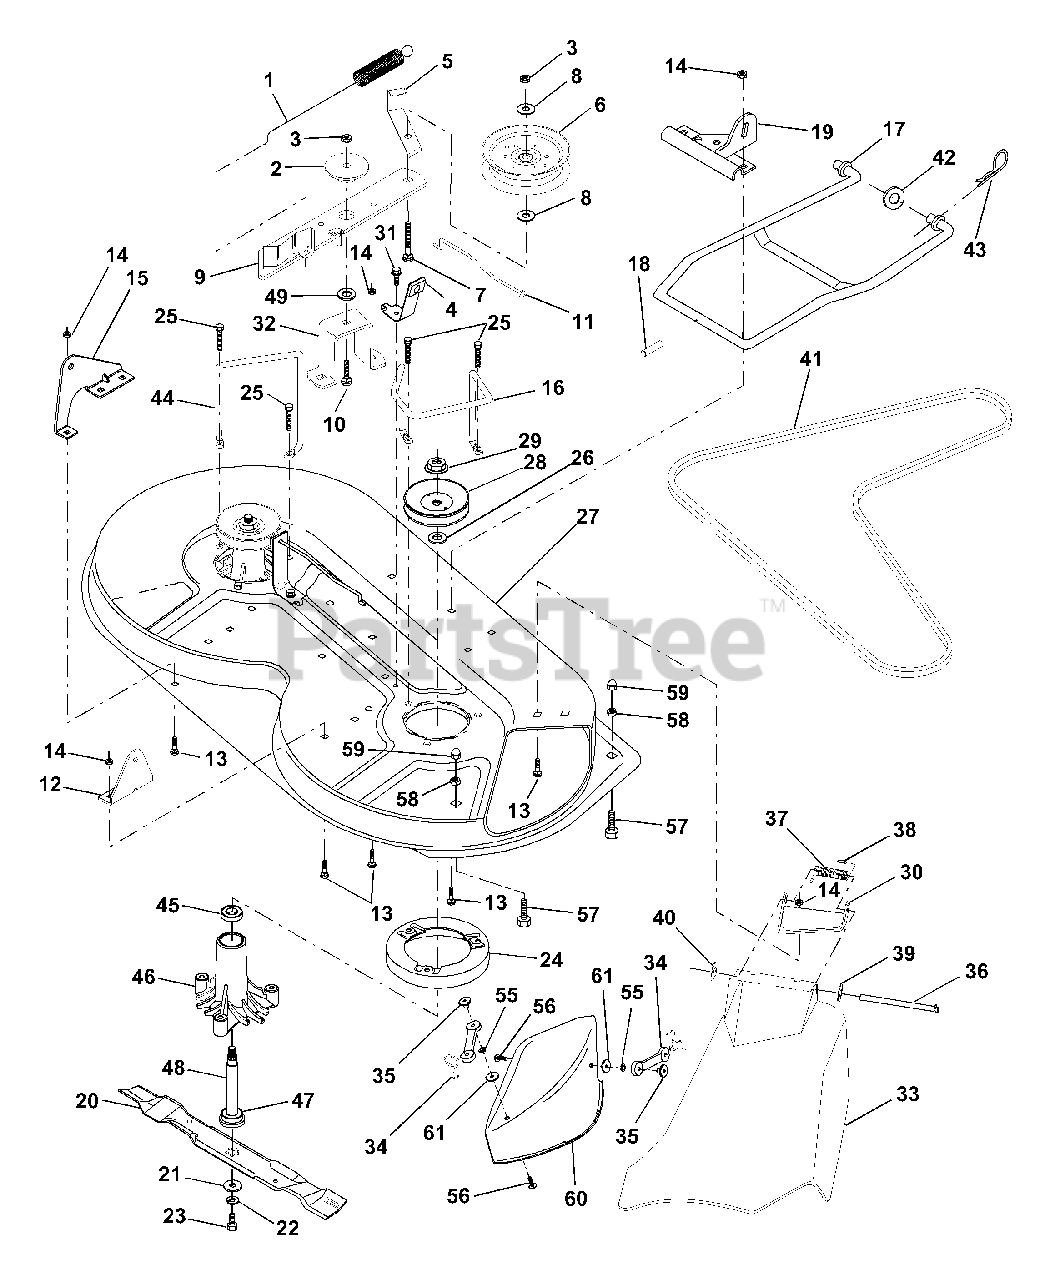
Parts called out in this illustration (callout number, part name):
1	Spring, Mower Clutch
2	Spacer, Retainer
3	Nut, Crownlock 3/8-16
4	Brake Asm.
5	Guide, Belt Idler
6	Pulley, Flat Idler
7	Bolt, Carr. 3/8-16 x 1-3/4 Gr. 5
8	Washer 13/21 x 7/8 x 10 Ga.
9	Arm Asm., Idler Mower
10	Bolt, Carriage 3/8-16 x 1-1/4
11	Rod, Brake
12	Bracket, Lift R. H. Rear
13	Bolt, Carriage 5/16-18 x 3/4
14	Nut, Crownlock 5/16-18
15	Bracket, Lift L. H. Rear
16	Keeper, R. H.
17	Link, Asm. Mower Stabilizer
18	Pin, Drive
19	Bracket, Asm. Front
20	Blade Mulching
21	Washer, Hard
22	Washer, Lock 3/8
23	Bolt 3/8-24 x 1-1/4 Gr. 8
24	Stripper
25	Screw Thdrol Hex Hd
26	Washer .150 Thk.
27	Deck Assembly
28	Pulley, Mandrel
29	Nut, Flangelock 9/16
30	Bracket, Asm. Deflector
31	Screw, Hex Wsh. Thdrol. 5/16-18 x 1/2
32	Arm, Support Idler Mower
33	Deflector
36	Rod, Hinge
37	Spring, Torsion Deflector
38	Cap, Sleeve
39	Washer 11/32 x 5/8 x 16 Ga.
42	Washer 11/32 x 5/8 16 Ga.
43	Retainer, Spring
44	Keeper, L. H.
46	Housing Mandrel Vented
48	Shaft, Mandrel
49	Washer, Hardened
50	Mulcher Plate
51	Acorn Nut 5/16-18
52	Latch Hook
53	Nut, Weld
54	Washer #10
55	Washer, Lock #10
56	Screw
57	Bolt, Hex 5/16-18 x 1
58	Locknut 5/16-18
